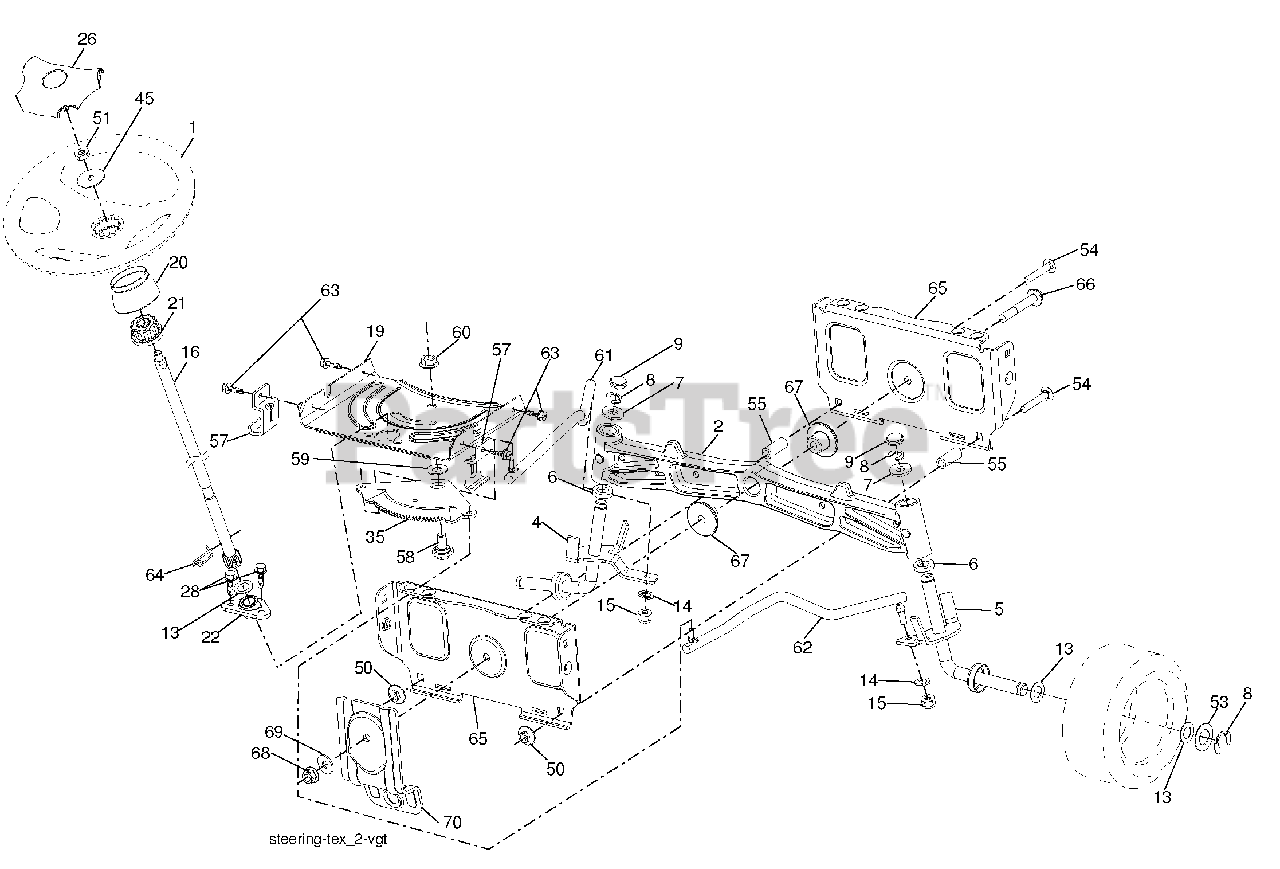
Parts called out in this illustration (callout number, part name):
1	Wheel, Steering
2	Axle Asm., Front
4	Spindle Asm., LH
5	Spindle Asm., RH
6	Bearing, Race Thrust Harden
7	Washer 25/32 x 1-5/8 x 16 Ga.
8	Ring, Klip #T5304-75
9	Cap, Spindle
13	Washer 25/32 x 1-1/4 x 16 Ga.
14	Washer, Lock Hvy Hlcl Spr 3/8
15	Nut, Crown Lock 3/8-24 unf
16	Shaft Steering
19	Plate Steering
20	Boot, Steering
21	Adapter, Wheel Steering
22	Bushing, Strg. Blk
26	Insert, Wheel Steering
28	Screw 3/8-16 x 3/4
35	Gear, Sector Plate
45	Washer 9/16 x 2-3/8 12 Ga.
50	Nut Lock 3/8-16 UNC
51	Nut Hex Jam Toplock 1/2-20 unf
53	Washer Hardened .793 x 1.637 x .060
54	Bolt Hex 3/8-16 UNC x 2-1/4
55	Spacer Brace Axle
57	Bracket Upstop
58	Bolt Shoulder Sector Pivot CFM
59	Washer Thrust Sector Steering
60	Nut Flange Lock 5/8-11
61	Draglink LH
62	Draglink, RH
63	Screw 5/16-18 x 3/4
64	Retainer Clip Spring Steering
65	Brace Axle Front
66	Bolt Hex Fghd 7/16-14 x 3 Serr
67	Bushing PM Front Axle
68	Nut Lock Flange 7/16-14 Gr. 5
69	Washer 1.5 x .505 x .118
70	Bracket Deck Susp. Front
